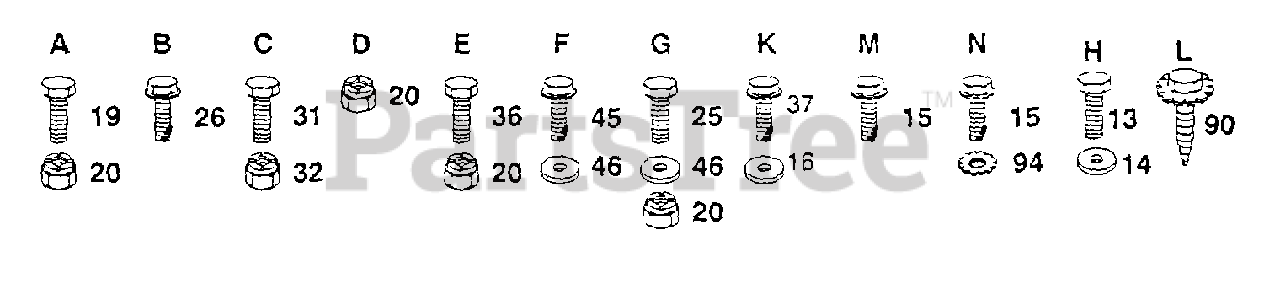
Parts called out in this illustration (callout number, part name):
13	"BOLT,HEX"
14	WASHER T
15	SCREW
16	LOCKWASHER
19	BOLT
25	BOLT
26	SCREW
31	BOLT
37	BOLT
45	SCREW
46	WASHER
94	LOCKWASHER
